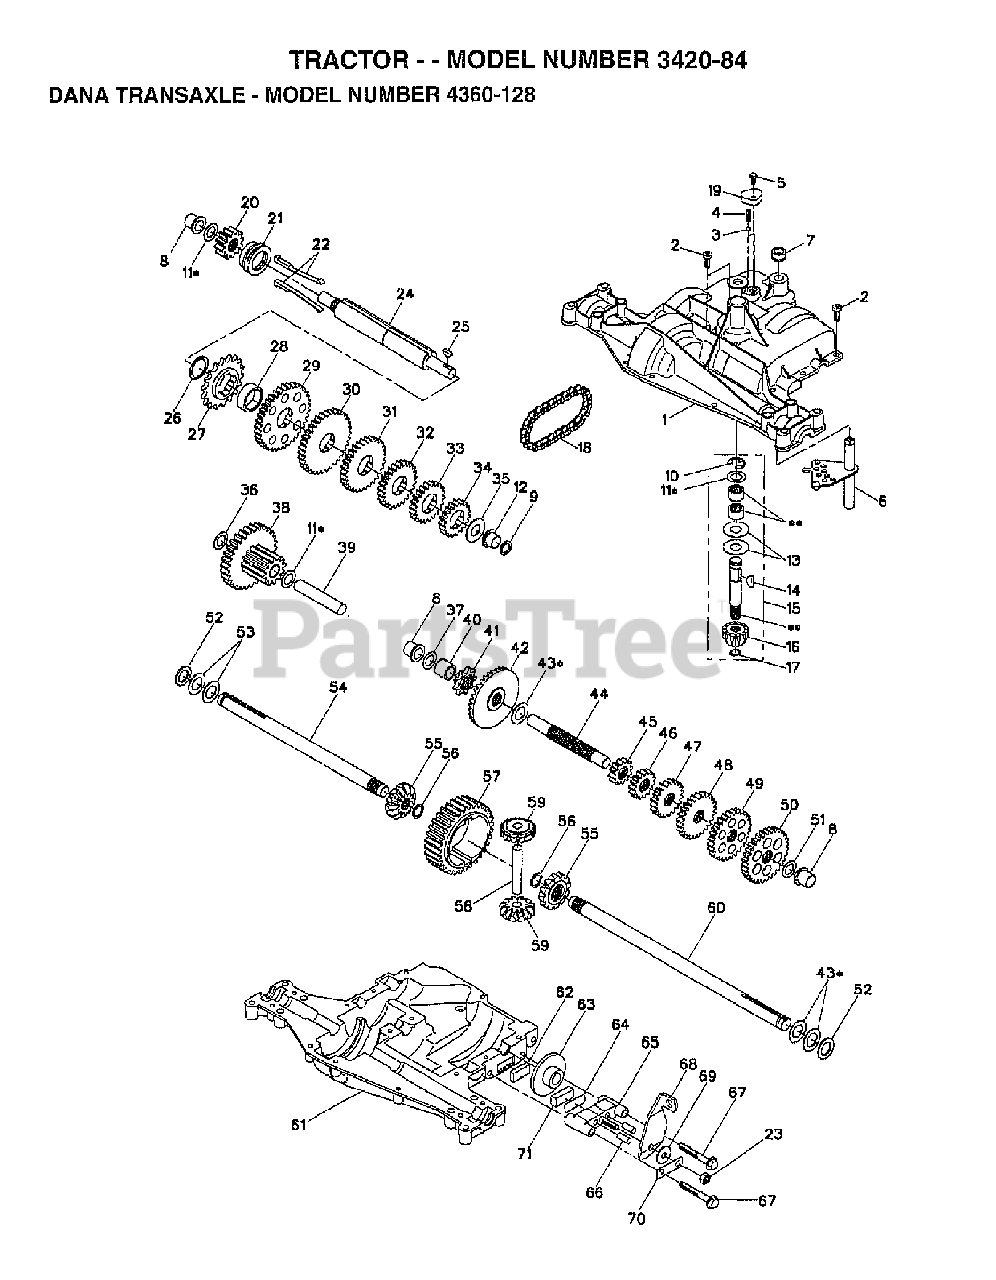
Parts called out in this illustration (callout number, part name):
2	Poulan TBD
4	SPRING, DETENT
6	SHIFTER KIT
10	Poulan TBD
11	SHIM.KIT.DANA.4689
12	BEARING.FLANGE (DANA 5511)
13	WASHER.PLAIN..632X1.38X.046
14	KEY.WOODRUFF.DANA
17	RING RETAINING
18	CHAIN 24 PITCH LT
22	ASSEMBLY KIT, CLUTCH KEYS
23	LOCKNUT
24	SHAFT INTERM DANA
26	RING, RETAINING LT
27	SPROCKET 18T
29	GEAR, SPUR 37 TEETH
30	GEAR, SPUR 35 TEETH
32	GEAR, SPUR 25 TEETH
33	GEAR, SPUR 22 TEETH
36	WASHER 045
37	WASHER 031
39	SHAFT IDLER
41	SPROCKET 9T LT
44	SHAFT, DRIVE
45	GEAR SPUR 12 TEETH
49	GEAR, SPUR 28 TEETH
50	GEAR, SPUR 31 TEETH
52	NEOPRENE.WASHER.DANA
53	WASHER 031
62	PUCK, FRICTION
63	BRAKE DISC T
64	SPACER LT
69	WASHER, PLAIN .321 X 1.00X.055
71	PUCK, FRICTION
72	SHELL, GREASE
